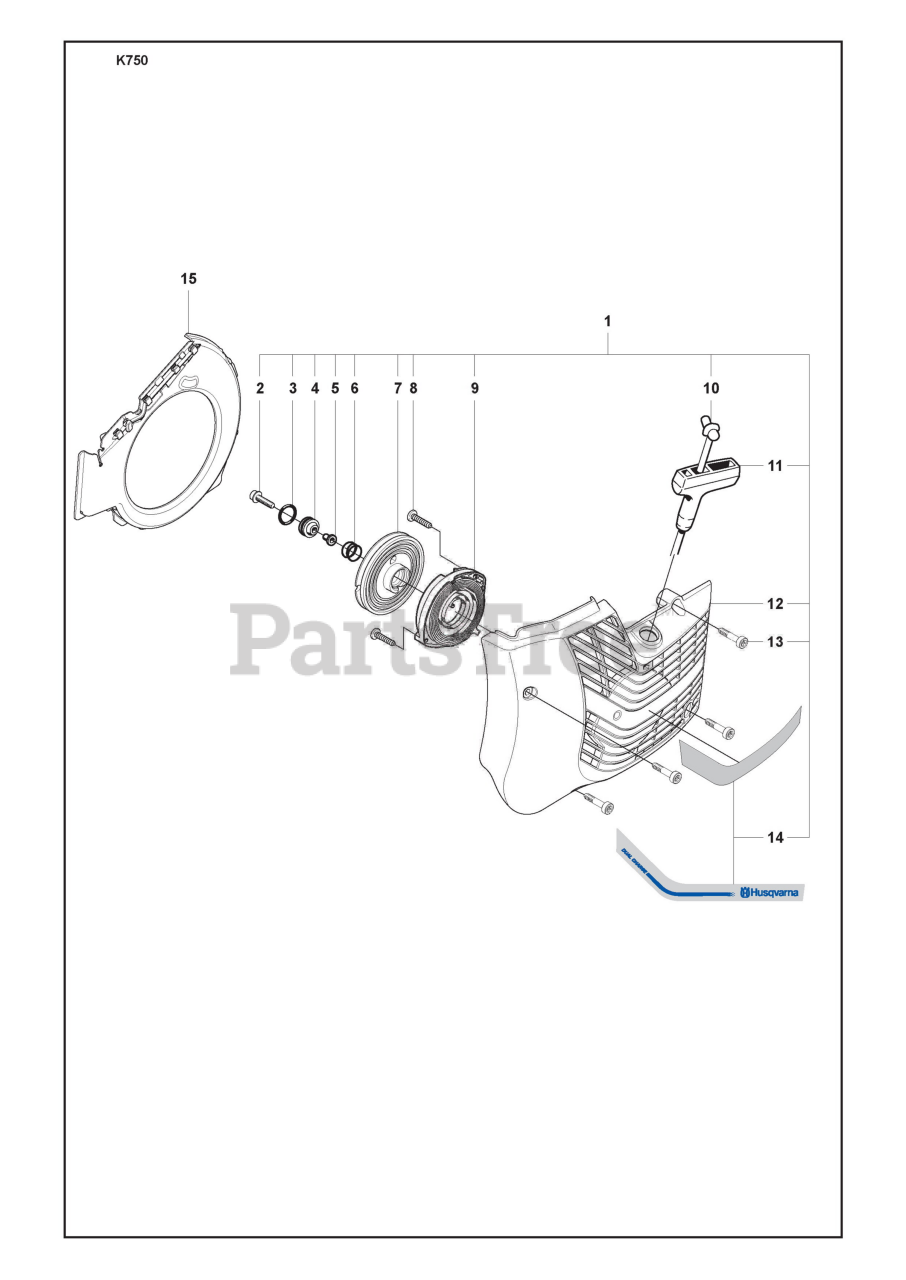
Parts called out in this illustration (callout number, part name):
1	STARTER
2	SCREW
4	GROMMET
5	SPACING SLEEVE
6	COMPRESSION SPRING
7	STARTER PULLEY
9	RECOIL SPRING
10	STARTER CORD
11	STARTER HANDLE
12	STARTER COVER
14	LABEL
15	AIR CONDUCTOR
